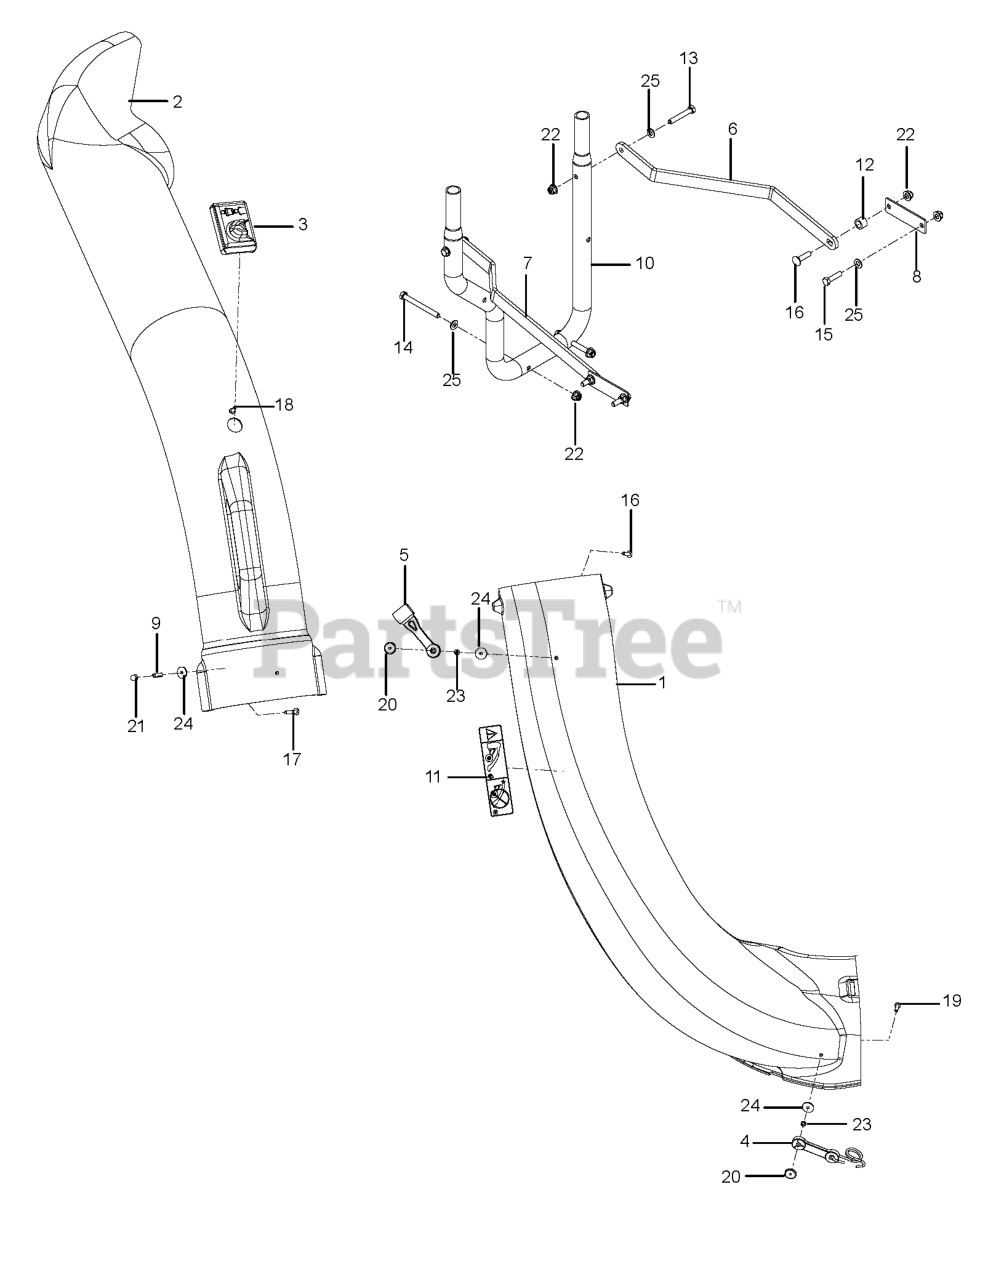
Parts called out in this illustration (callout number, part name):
1	CHUTE.BAGGER.LOWER.54"
2	CHUTE.COLLECTION.UPPER
3	DUMP BAG INDICATOR
4	LATCH ASSY TBR
5	HOOD LATCH
6	STRAP.SUPPORT.LT.BLK
7	STRAP.SUPPORT.RT.BLK
8	REINFORCEMENT PLATE BLK
9	BSHG .202X.75 LG SPLIT ZD SPEC
10	MOUNT.TUBE.COLLECTIONS
11	DECAL, CATCHER
12	SPACER,391"ID.375",L.078",WALL
13	HCS 5/16-18X2
14	HCS 5/16-18 X 3 1/4
15	HCS 5/16C X 1 1/4
16	BOLT, CARRIAGE 5/16X1-1/4
17	SCREW #10-24 X 1-1/8 ZD SPEC
19	SCREW #10-24 X 5/8
20	NUT 10-24 WELD PLATED
21	NUT 10-24 ACORN ZD
22	5/16-18 NYLOC FLANGE NUT
23	WASHER - 3/16 LOCK ZD
25	WASHER
